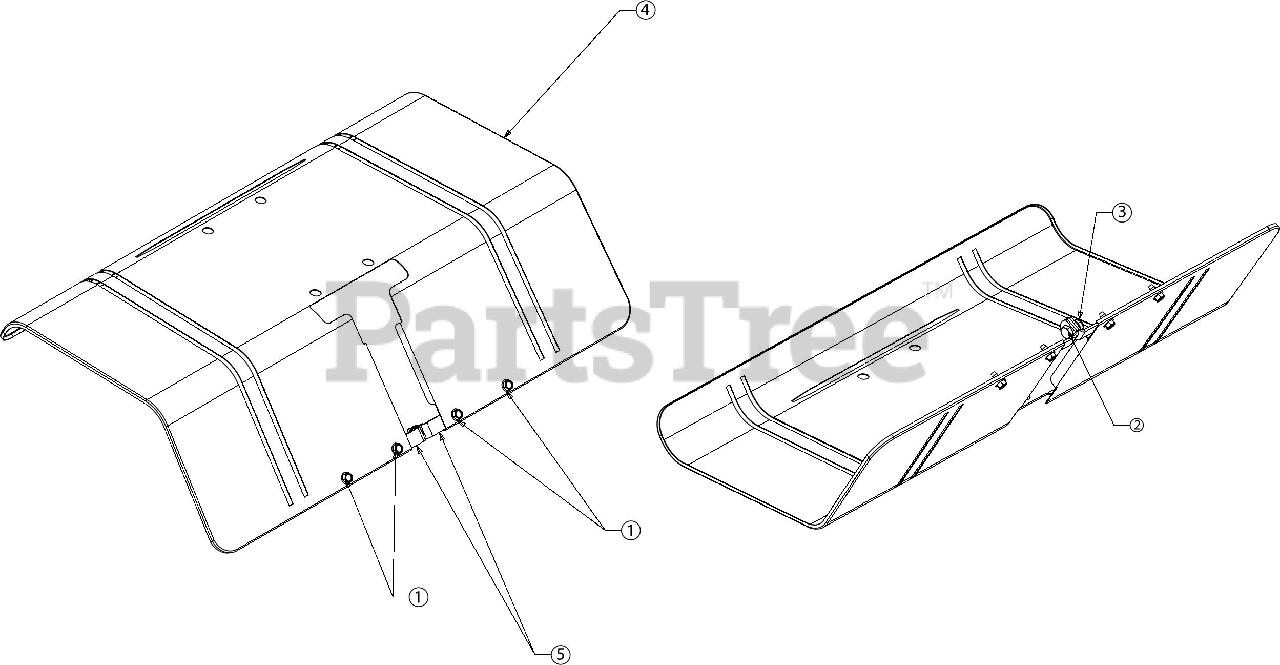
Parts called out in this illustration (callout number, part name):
1	SCREW 1/4-20 X.500
2	SCREW 5/16-18 x .75 GR5
3	FLANGE LOCK NUT 5/16-18
5	TINE SHIELD BRACKET
